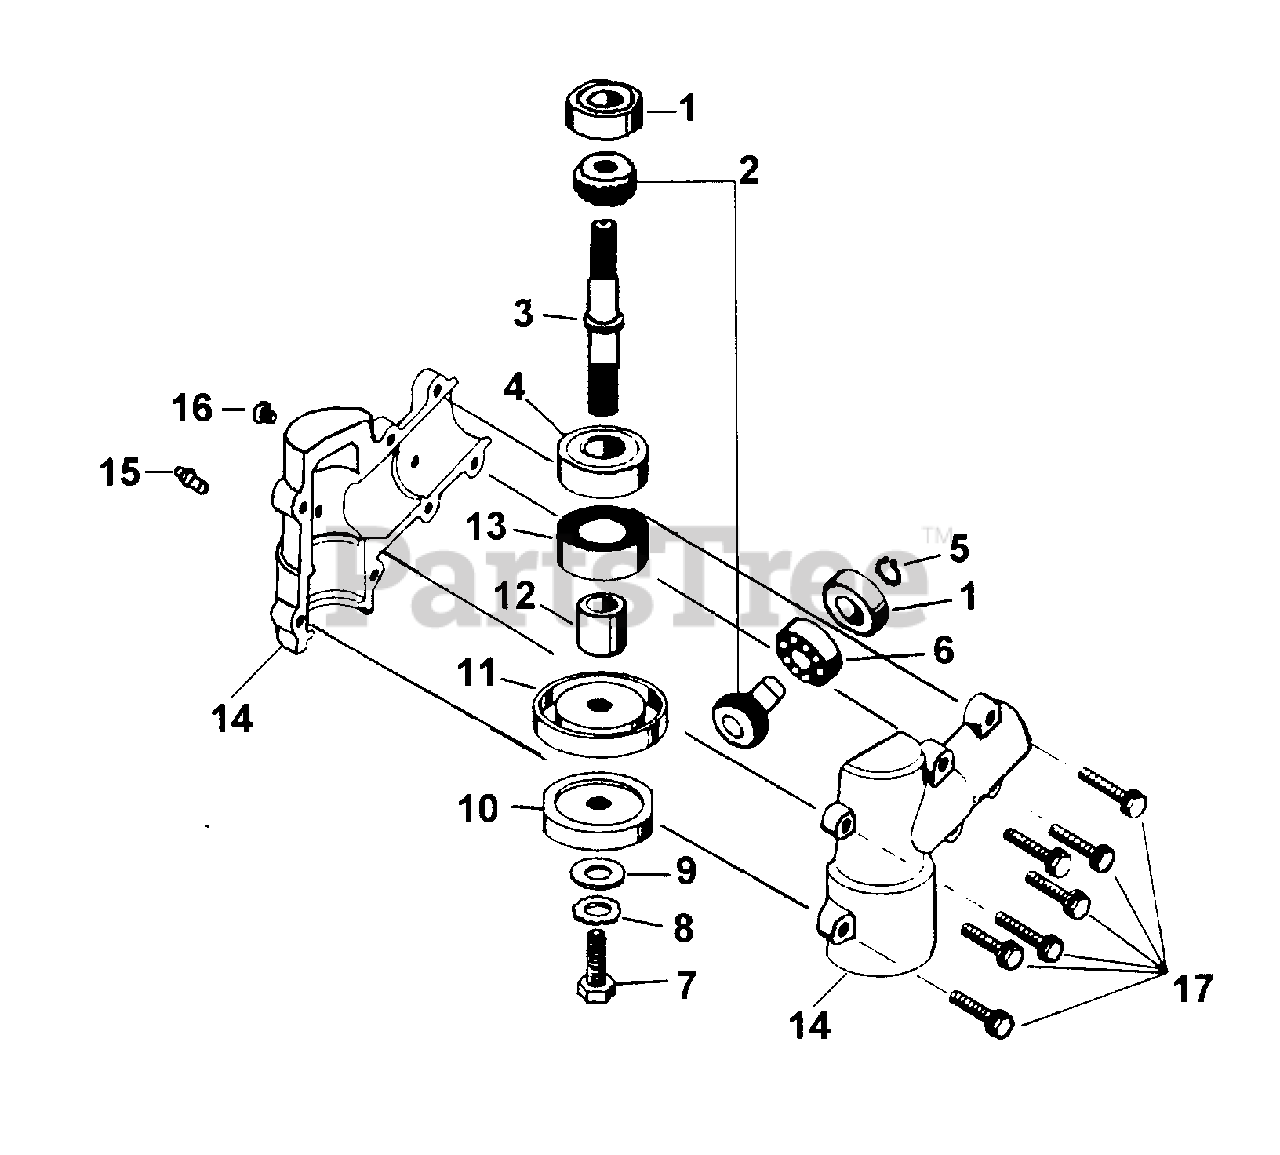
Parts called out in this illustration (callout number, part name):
1	BEARING
2	GEAR SET KIT
3	SHAFT, GEAR
4	BEARING
5	SNAP RING
6	BEARING
7	BOLT
8	WASHER
13	BEARING
14	HOUSING SET
15	GREASE FITTING
16	SCREW, SELF TAPPING
17	SCREW, SELF TAPPING
